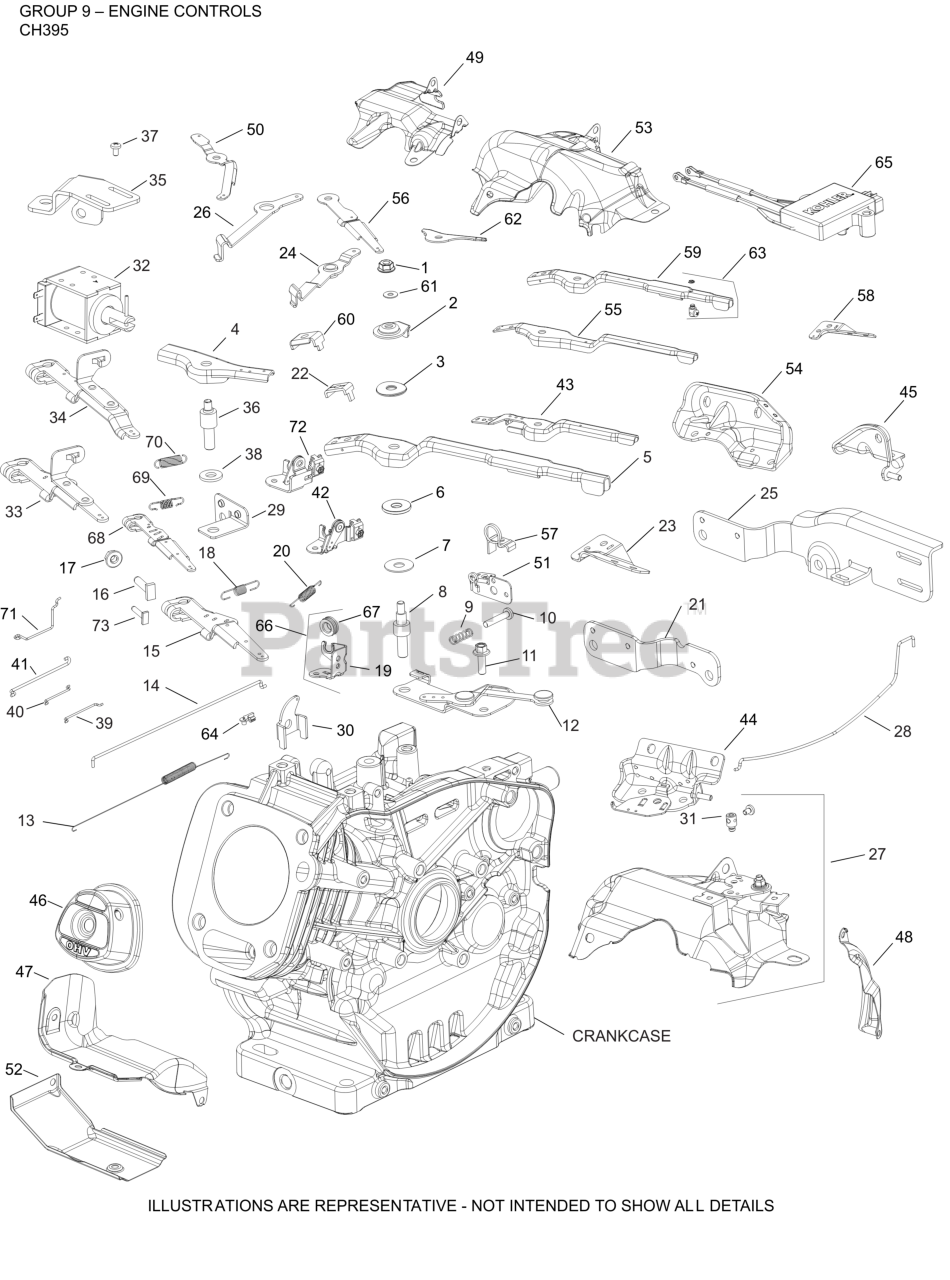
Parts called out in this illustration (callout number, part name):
1	NUT, HEX FLANGE LOCK (M6)
2	WASHER, CONTROL LEVER
3	WASHER, SPRING
5	CONTROL LEVER ASSEMBLY
6	WASHER, NYLON CONTROL LEVER
7	WASHER, FLAT
8	STUD, CONTROL LEVER
9	SPRING, COMPRESSION
10	SCREW, SPEED ADJUSTING
12	BRACKET, CONTROLS ASSY
13	SPRING, LINKAGE
14	LINKAGE, GOVERNOR
15	KIT, GOVERNOR LEVER
16	SCREW, RECTANGLE HEAD (M6)
17	NUT, HEX FLANGE (M6) - USE 14 100 16-S
18	SPRING, GOVERNOR
20	SPRING, THROTTLE RETURN
22	CLAMP, CABLE
23	BRACKET, BOWDEN CABLE ASSY
